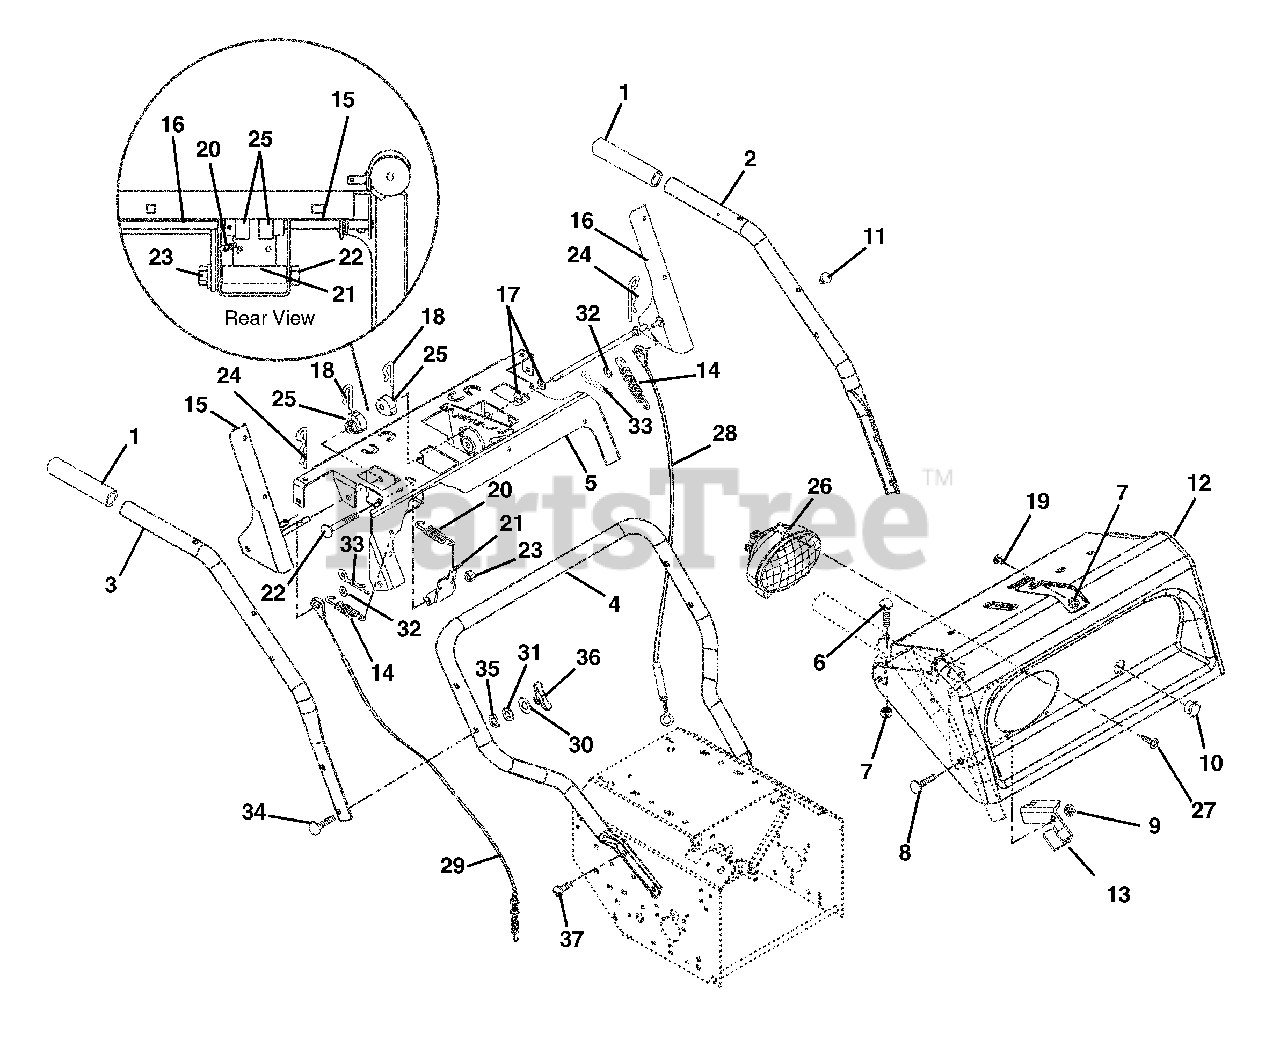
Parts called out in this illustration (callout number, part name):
1	HANDLE GRIP
2	HANDLEBAR, UPPER-RH
3	HANDLEBAR, UPPER-LH
4	HANDLEBAR, LOWER
5	PANEL, SUB
6	BLT-RDHDXLSQNK.25-20X1.25 G5ZC
7	@NUT-LK-CTR .25-20 YWZC
8	@BLT-RDHDSQNK .31-18X1.75 G5YZ
9	@NUT-LK-CTR .31-18 YWZC
10	SNAP BUSHING
12	PANEL W/DECAL - 824
13	BRACKET, CABLE ANCHOR
14	SPRING-EXT .056X.50X3.76
15	LEVER, RH-COATED
16	LEVER, LH-COATED
17	@WSHR-FL-STL.344X.688X.065YWZC
18	PIN, SPRING CLIP
19	BLT-RDHDSQSHNK.25-20X.50 YWZC
20	SPRING-EXT .047X.438X1.45
21	ARM, INTERLOCK
22	@BLT-HEX .38-16X3.00 GR5 YWZC
23	@NUT-LK-CTR .38-16 YWZC
24	PIN-HAIR, ENDRIES #25 YWZC
25	CAM, INTERLOCK
26	HEADLAMP, OVAL W/ 1156 BULB
27	SCR-TAP 10-16X.75 HI-LO PPH
28	CABLE, TRACTION
29	CABLE, AUGER
30	WSHR-FL-STL .328X.875X.062YWZC
31	WSHR-LK .312X.097 HVY YWZC
32	@WSHR-FL-STL.281X.62X.065 YWZC
33	PIN-HAIR INT .06X.18X.77
34	@BLT-RDHDSQNK .31-18X2.25 G5YZ
35	WASHER,SADDLE-.320 X.937 X.062
36	KNOB - WING .312-18 UNC
37	BLT SERHFWH .31-18X.62 GR5YWZC
